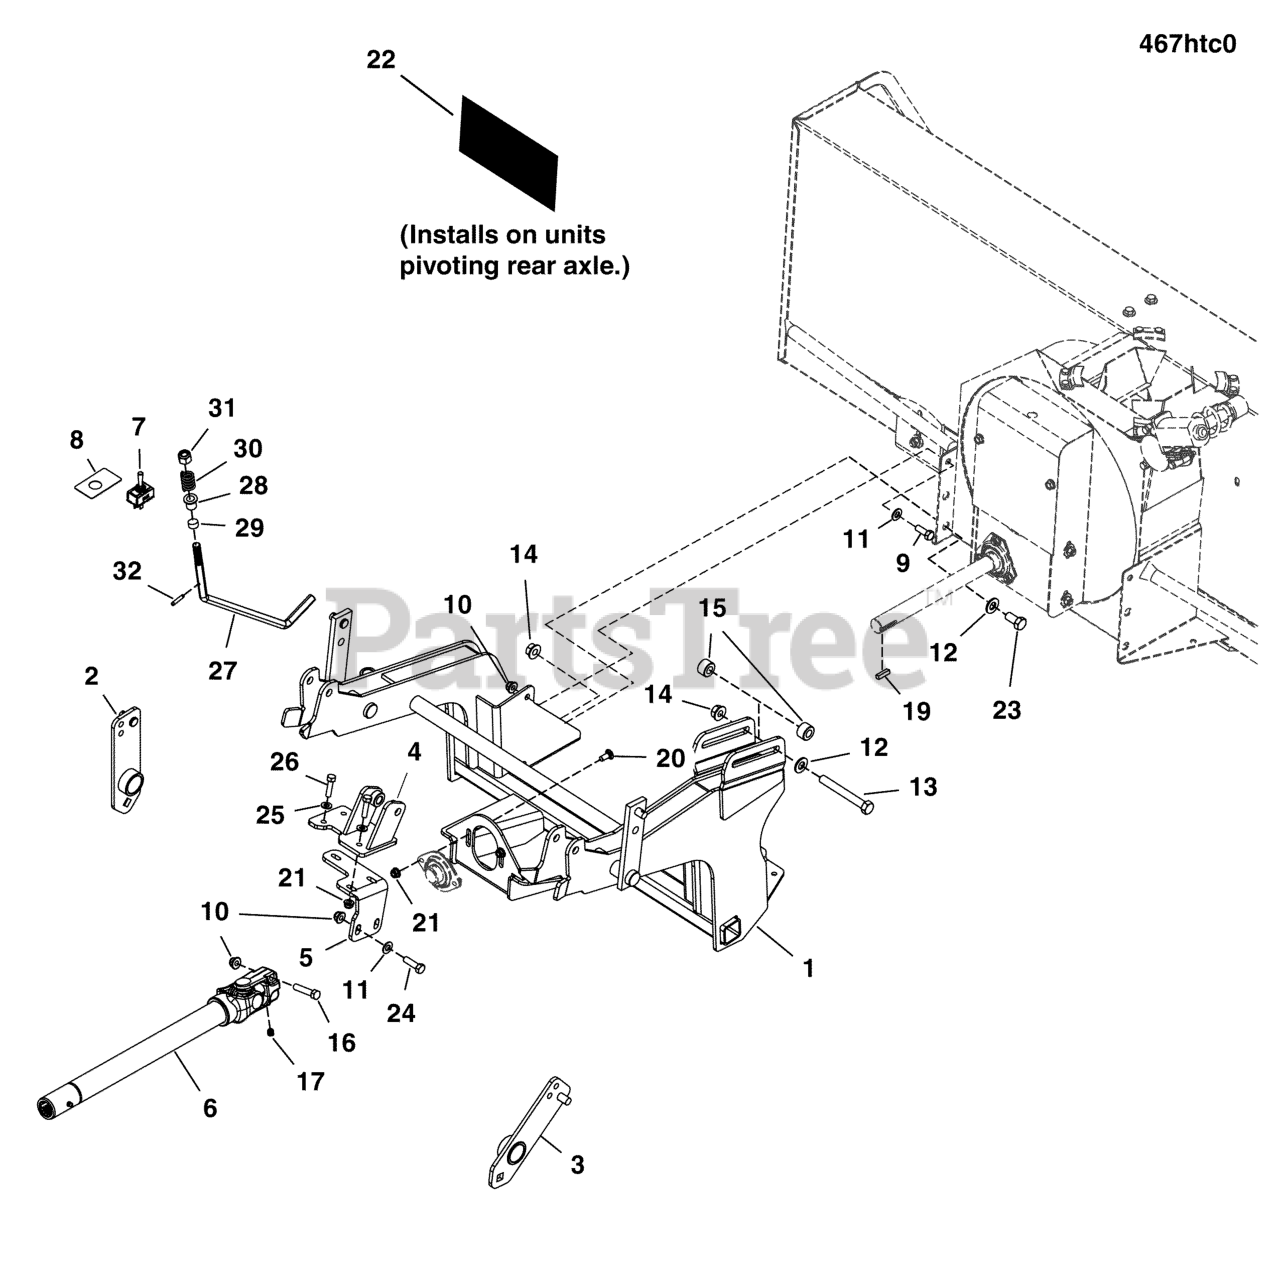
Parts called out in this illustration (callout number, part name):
1	WELD, MNT, SNOW THROWER, S800X - BLK
2	WELD, SPRING PVT, SNOW, LH - BLK
3	WELD, SPRING PVT, SNOW, RH - BLK
4	WELD, ACTUATOR MOUNT - BLK
5	PLATE, ACTUATOR MNT SUPPORT - BLK
6	1/2 DRIVE SHAFT SEALED, SNOW THROWER
7	Switch, Electric Actuator
8	DECAL, CHUTE ROTATION, S800X
9	BOLT, 3/8-16 X 1" GD5 CZ
10	NUT, 3/8 - 16 HEX NYLOCK FLANGE
11	WASHER, 3/8 SAE
12	WASHER, 1/2 SAE
13	BOLT, 1/2-13 X 4" GD5 CZ
14	NUT, Hex Flange, Nylock, 1/2-13
15	SPACER, .52 X 1.00 X .63, YZ
16	BOLT, 3/8-16 X 1-3/4" GD5 CZ
17	SET SCREW, 3/8-16 X 3/8
18	KEY, 1/4" SQ. X 1-1/4
19	KEY, 1/4 SQ X 1
20	BOLT, 5/16-18 X 3/4, CARRIAGE, GD5, CZ
21	NUT, 5/16-18 HEX NYLOCK FLANGE NUT
22	REFLECTOR-REAR RED 1.38 X 3.00
23	BOLT, 1/2-13 X 1-1/4 GD5 CZ
24	BOLT, 3/8-16 X 1-1/4" GD5 CZ
25	WASHER, 5/16" SAE
26	BOLT, 5/16-18 X 1-1/4" GD5 YZ
27	KICK STAND, SNOW THROWER, S800X
28	FLANGED BUSHING, 1/2ID X 5/8OD X 3/4"LG
29	BUSHING, .510 X .625 X .500
30	SPRING-COMP, .625 ID X 1.31 LG X .105 WR
31	NUT, Hex, Nylon Lock, 1/2-20
32	PIN-SPRING .188 X 1.00 PLN SAE 1095
